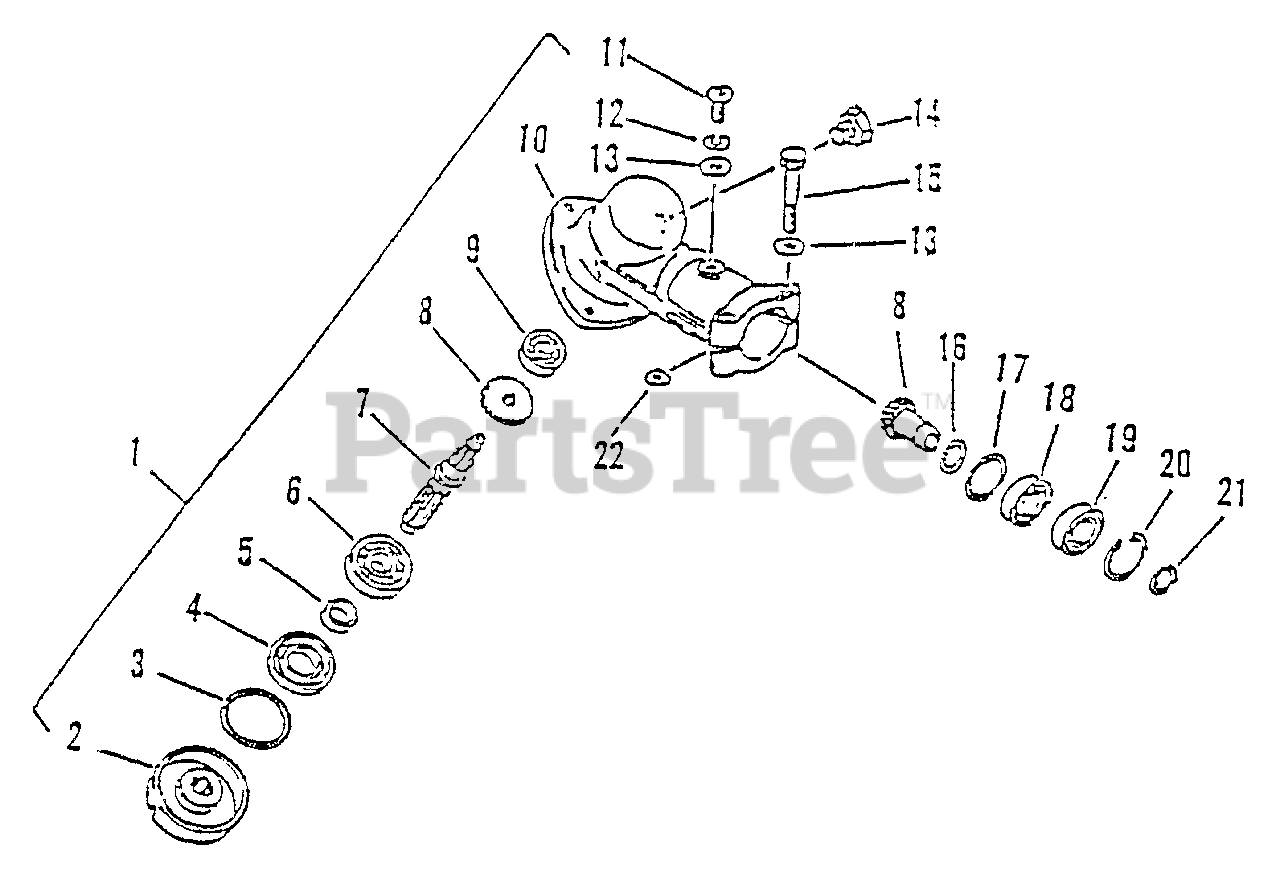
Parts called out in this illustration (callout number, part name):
1	GEAR CASE ASSY
2	PLATE, ADAPTOR - UPPER
3	RING, SNAP Ø32
4	SEAL, OIL
6	BEARING, BALL - 6201 C3
7	SHAFT, GEAR
8	GEAR SET
9	BEARING, BALL 609
10	CASE, GEAR
11	SCREW 5×10
12	WASHER, SPRING 5
13	WASHER, FLAT 5.5×10×0.8
14	BOLT 8×8 SP
15	BOLT 5×35 SP
18	BEARING, BALL 6900
19	BEARING, BALL 6900Z
20	RING, SNAP Ø22
21	RING, SNAP Ø12
